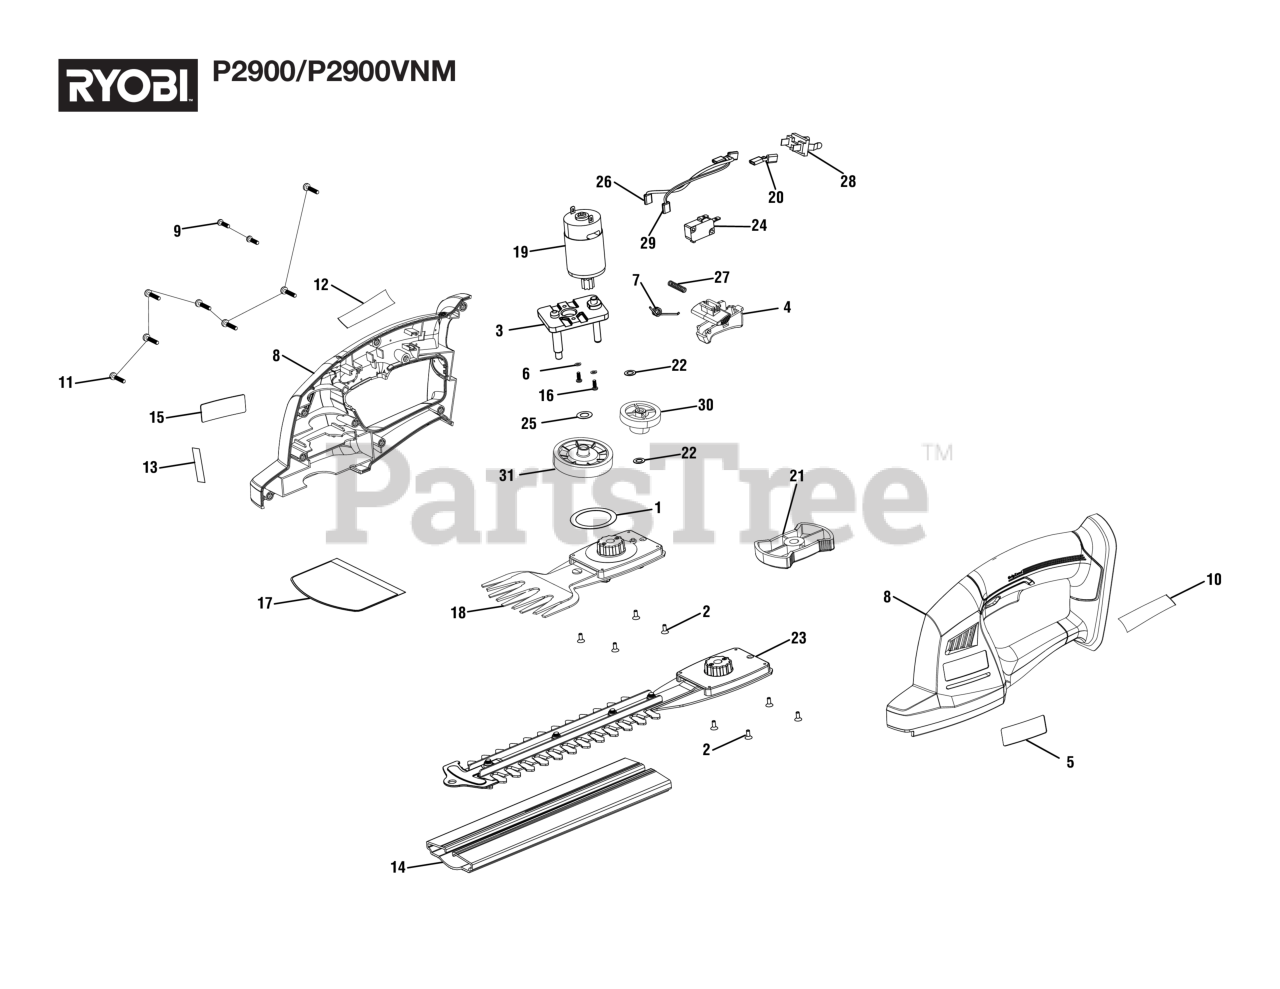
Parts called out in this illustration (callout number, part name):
2	Screw (M3 x 8.5 mm, Flat Hd.)
3	Motor Mount Assembly
4	Trigger Assembly, ABS
5	Label, Logo
6	Washer (OD5.7 x ID3.1 x 0.8t)
7	Trigger Spring
8	Housing Assembly (P2900VNM)
9	Screw (M3.5 x 12 mm, Pan Hd.)
10	Danger Label (Left, P2900VNM)
11	Screw, M36.5x16mm, Pan. Head, Steel
12	Warning Label (Right, P2900VNM)
13	Label, Warning, Icon
15	Data Label (P2900VNM)
16	Screw, M3x8mm, Steel
18	Grass Shear Blade Assembly
19	Motor and Pinion Assembly
20	Wire, Red Lead, 75 mm
21	Knob Assembly
22	Washer (M6, ID6.2 x 11OD x 0.3t)
23	Hedge Trimmer Blade Assembly
24	On/Off Switch
25	Washer, OD15xID8.4xT0.3
26	Wire, Black Lead, 150 mm
27	Compression Spring
28	Contact Plate
29	Wire, Red Lead, 150 mm
30	Step Gear
